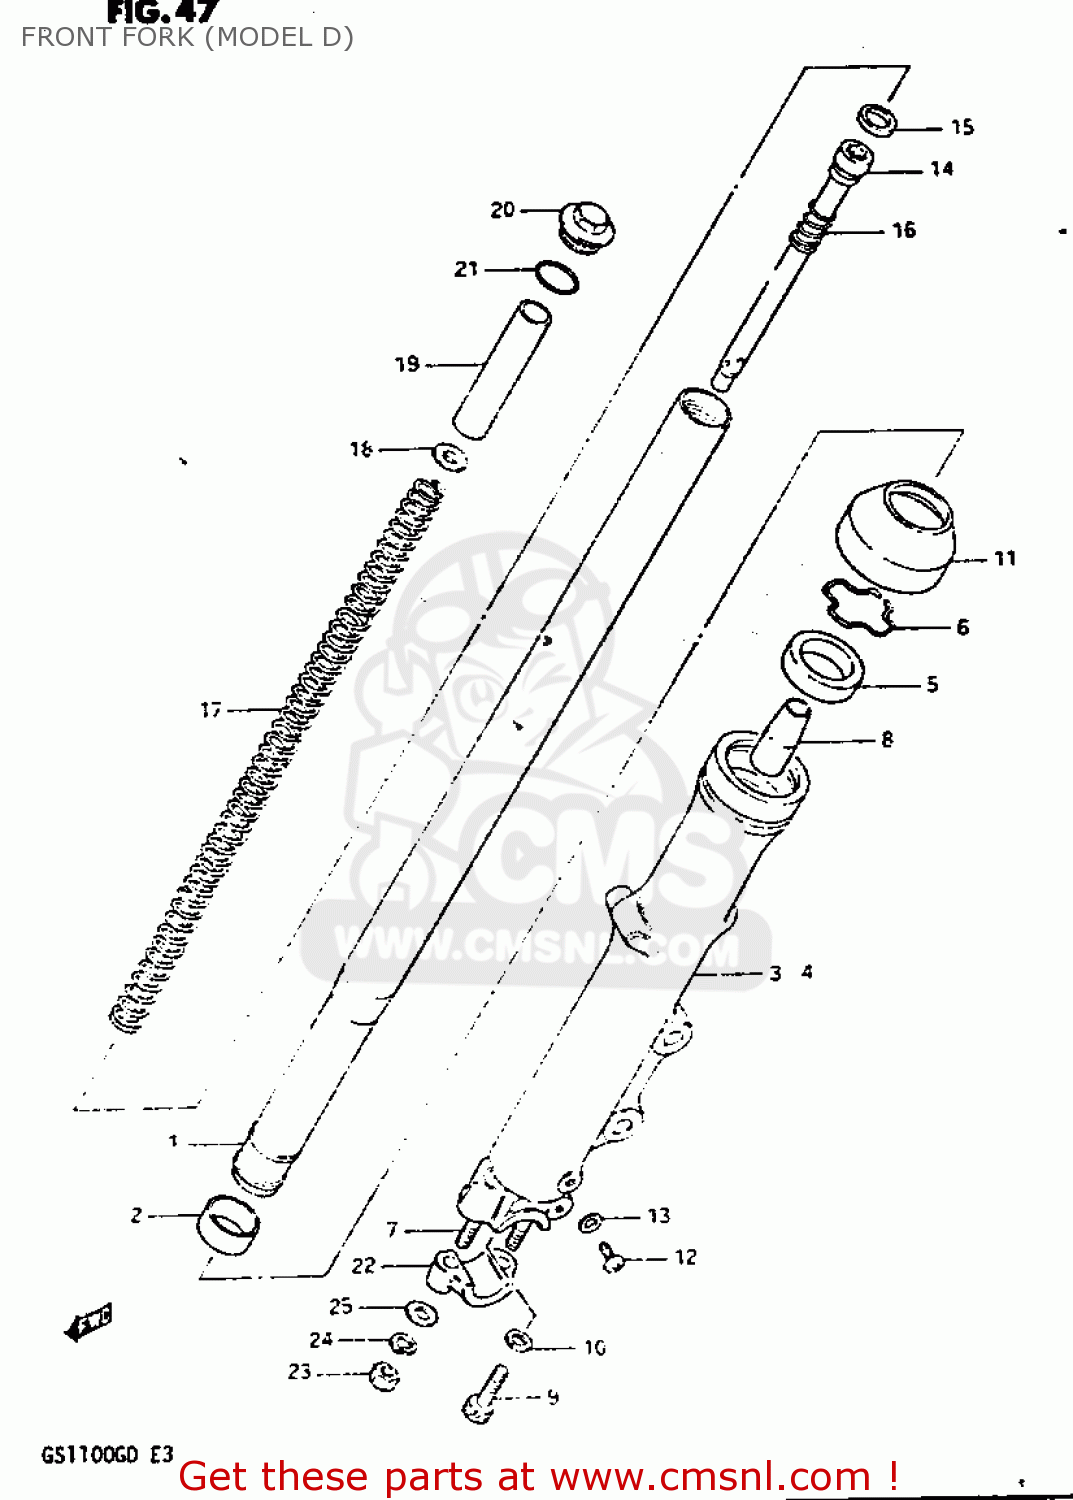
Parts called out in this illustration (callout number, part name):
1	TUBE,FORK,INNER
2	PISTON
3	TUBE,FORK,OUTER,RIGHT
4	TUBE,FORK,LEFT,OUTER
5	OIL SEAL,FRONT FORK
6	RING,STOPPER
7	STUD 8X30
8	PIECE,OIL LOCK
9	BOLT,FORK CYLINDER(10X25)
10	GASKET (NAS)
11	SEAL,DUST
12	SCREW
13	GASKET,DRAIN,PLUG (NAS)
14	CYLINDER,FRONT FORK
15	RING,PISTON
16	SPRING,REBOUND
17	SPRING,FRONT FORK
18	GUIDE,FRONT FORK SPRING C
19	SPACER,SPRING
20	CAP,FORK INNER TUBE
21	O RING
22	HOLDER,AXLE
23	NUT (8MM)
24	LOCK WASHER
25	WASHER
